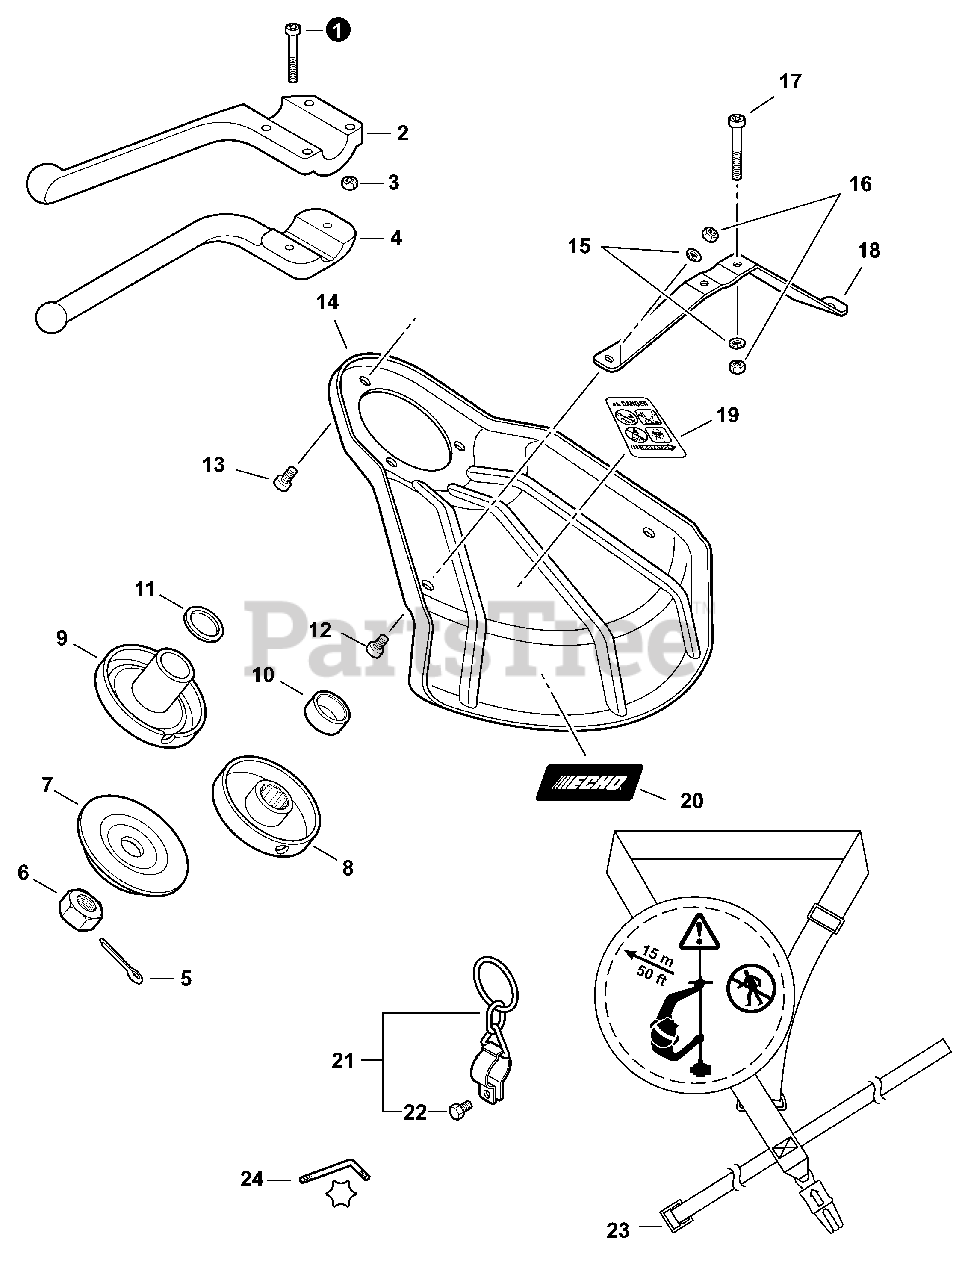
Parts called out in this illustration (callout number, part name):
1	BOLT, TORX 5×35
2	BAR, BARRIER
3	NUT M5
4	BAR, BARRIER
5	PIN, COTTER 2×22
7	PLATE, ADAPTOR - LOWER
8	PLATE, ADAPTOR - UPPER
9	PLATE, ADAPTOR - UPPER
10	SPACER 11.8×15×9
12	BOLT, TORX 5×8
13	BOLT, TORX 5×10
14	SHIELD, METAL DEBRIS
15	WASHER, SPRING 5
16	NUT M5
17	BOLT, TORX 5×35
18	BRACKET, SHIELD MOUNTING
19	LABEL, DANGER
20	LABEL, ECHO
21	HANGER SET, HARNESS
22	BOLT 5×12
23	HARNESS, SHOULDER
24	WRENCH, T27 80×30
